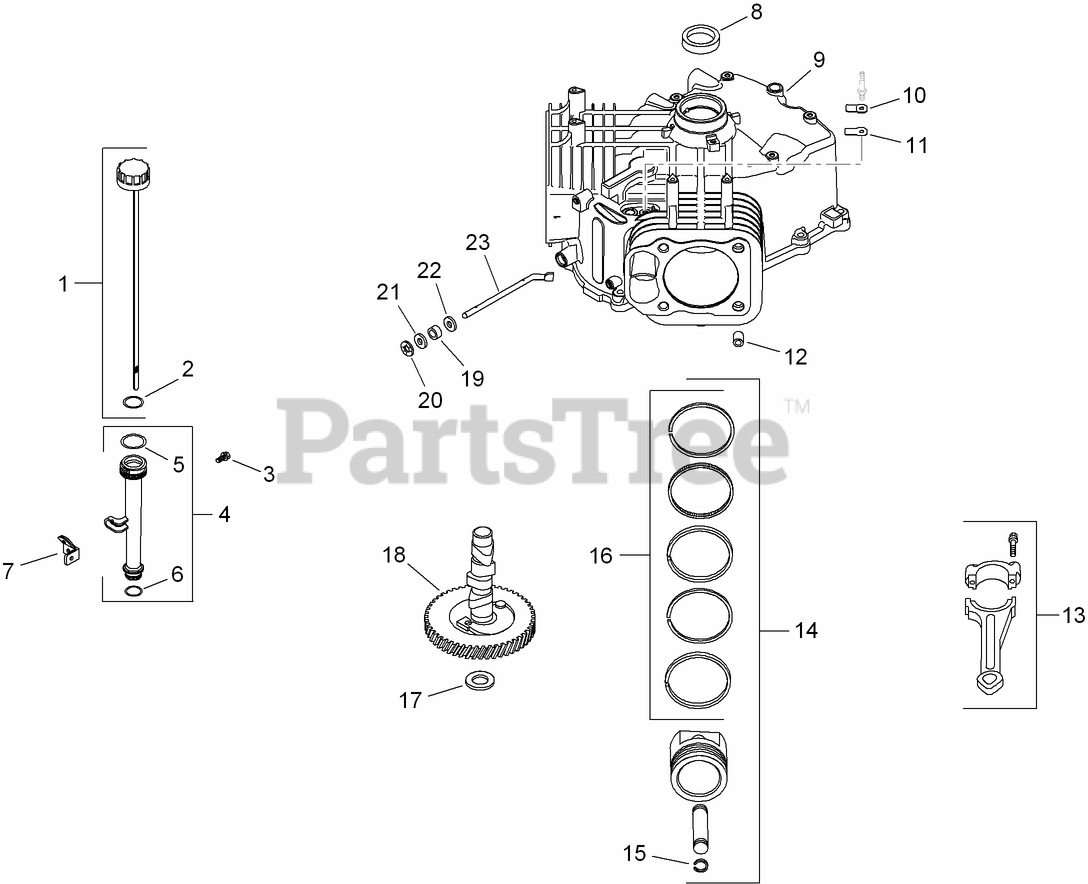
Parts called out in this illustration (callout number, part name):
1	Dipstick ASM (Includes 2)
2	O-RING
3	SCREW-FLG, THD FRM (M5X0.8X13)
4	OIL FILL TUBE ASM
5	O-RING
6	O-RING
7	BRACKET-TUBE, OIL FILL
8	SEAL-OIL (HELIX LIP)
9	SHORTBLOCK (SV710-740)
10	RETAINER-REED, BREATHER
11	REED-BREATHER
12	PIN-LOCATING
13	ROD-CONNECTING (STD)
14	PISTON W/RING SET (STD) (INCLUDES REF 8, 17)
14	PISTON W/RING SET (.08) (USE 25 874 02-S KIT)
14	PISTON W/RING SET (.25)
15	RETAINER-PIN, PISTON
16	PISTON RING SET (STD)
16	PISTON RING SET (.25)
17	SHIM-CAMSHAFT (WHITE .028)
17	SHIM-CAMSHAFT (BLUE .03)
17	SHIM-CAMSHAFT (RED .032)
17	SHIM-CAMSHAFT (YELLOW .034)
17	SHIM-CAMSHAFT (GREEN .036)
17	SHIM-CAMSHAFT (GRAY .038)
17	SHIM-CAMSHAFT (BLACK .04)
18	CAMSHAFT KIT (INCLUDES 25 357 14-S)
19	SEAL-CROSS SHAFT, GOVERNOR
20	RETAINER-RING
21	WASHER-FLAT (9MM)
22	WASHER-FLAT (11/32)
23	SHAFT-CROSS, GOVERNOR
